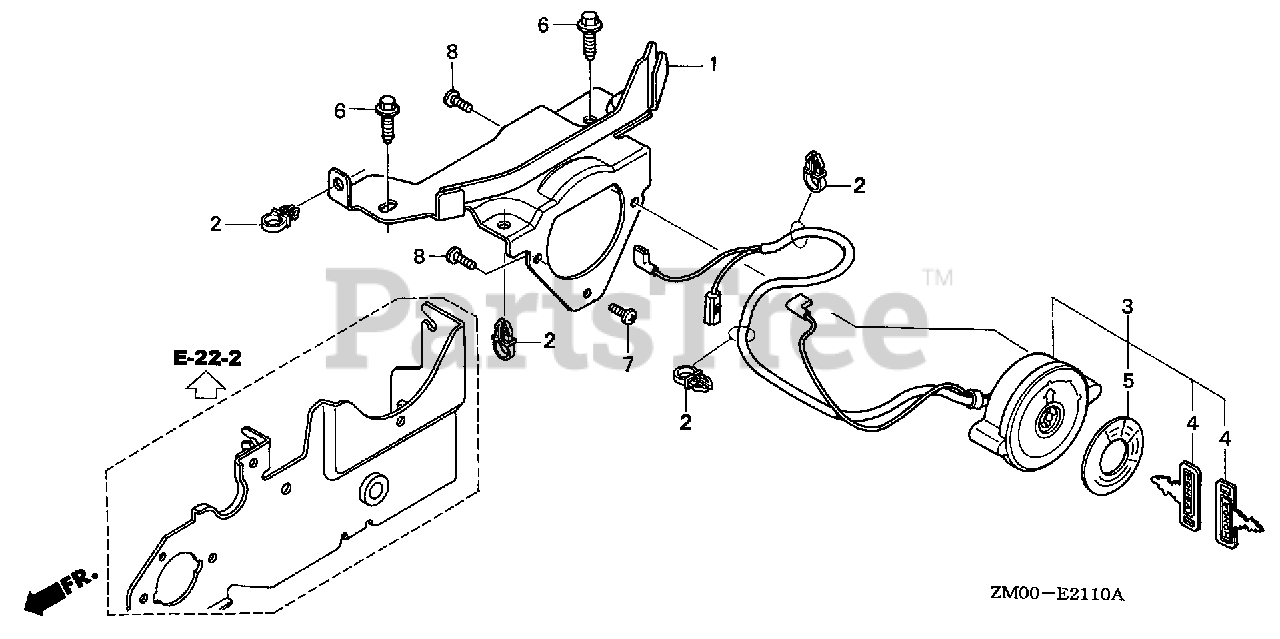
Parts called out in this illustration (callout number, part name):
1	PLATE, SIDE
2	HOLDER, WIRE
3	SWITCH ASSY., COMBINATION
4	KEY, COMBINATION SWITCH
5	MARK, ENGINE SWITCH (NOT AVAILABLE)
6	BOLT, FLANGE (6X12) (CT200)
7	SCREW, PAN (5X10)
8	SCREW, PAN (5X12)
